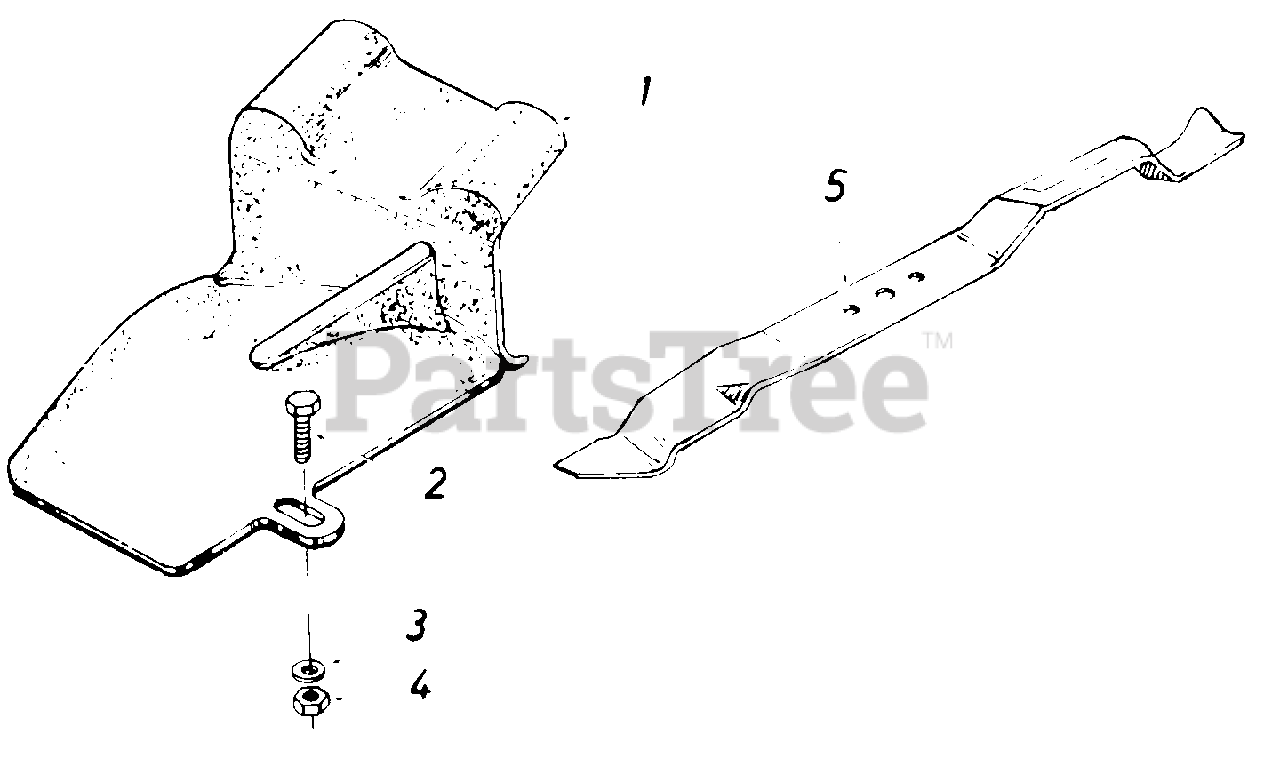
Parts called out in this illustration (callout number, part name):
1	Mulching Baffle
2	Hex Bolt 1/4-20 x .88" Lg.*
3	Belleville Wash. . 265 I.D. x. .75 O.D. x .093
4	Hex Jam Nut 1/4-2 Thd.
5	20" Mulching Blade
